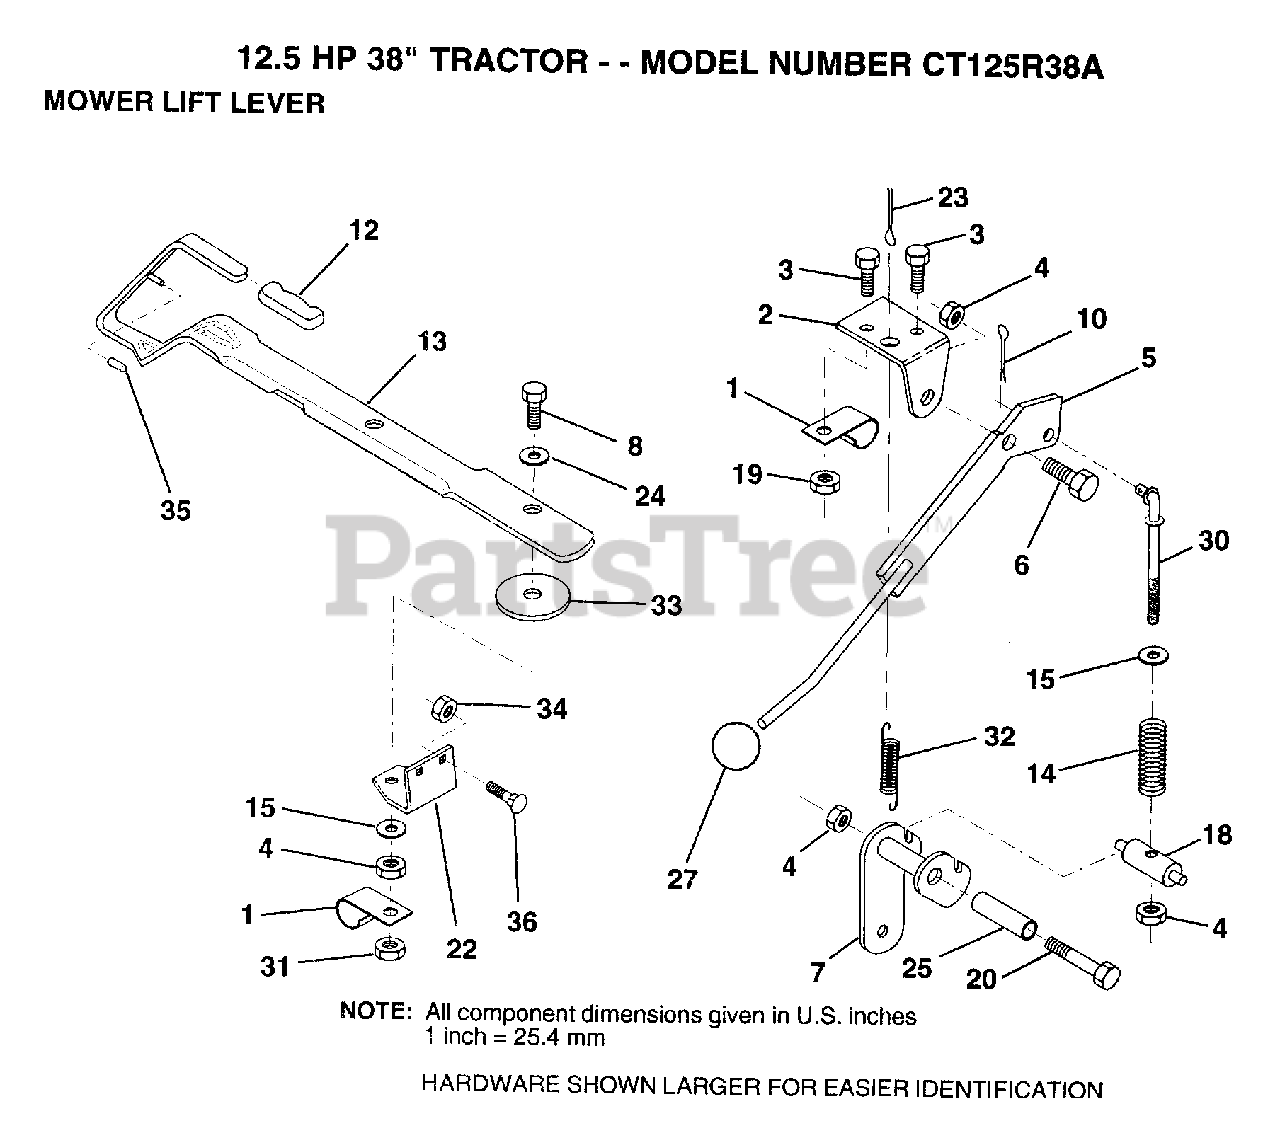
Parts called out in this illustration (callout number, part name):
1	"CLIP,INSULATOR"
2	BRKT CLUTCH
3	BOLT
5	CLUTCH LEVER AS
6	"BOLT, SHOULDER LT"
7	MWR CLUT ARM ASM
8	BOLT
10	COTTER PIN
12	GRIP HANDLE
13	LEVER LIFT LR
14	COMP CLUTCH SPRNG
15	WASHER HYT
18	TRUNNION
20	BOLT
22	LIFT LEVER BRKT
24	WASHER
25	TUBE SPACER
27	KNOB T (1/2-HOLE)
30	ROD TENSION CLUTC
31	LOCKNUT
32	SPRING EXT
33	WASHER T
35	VINYL CAP RED
36	BOLT
